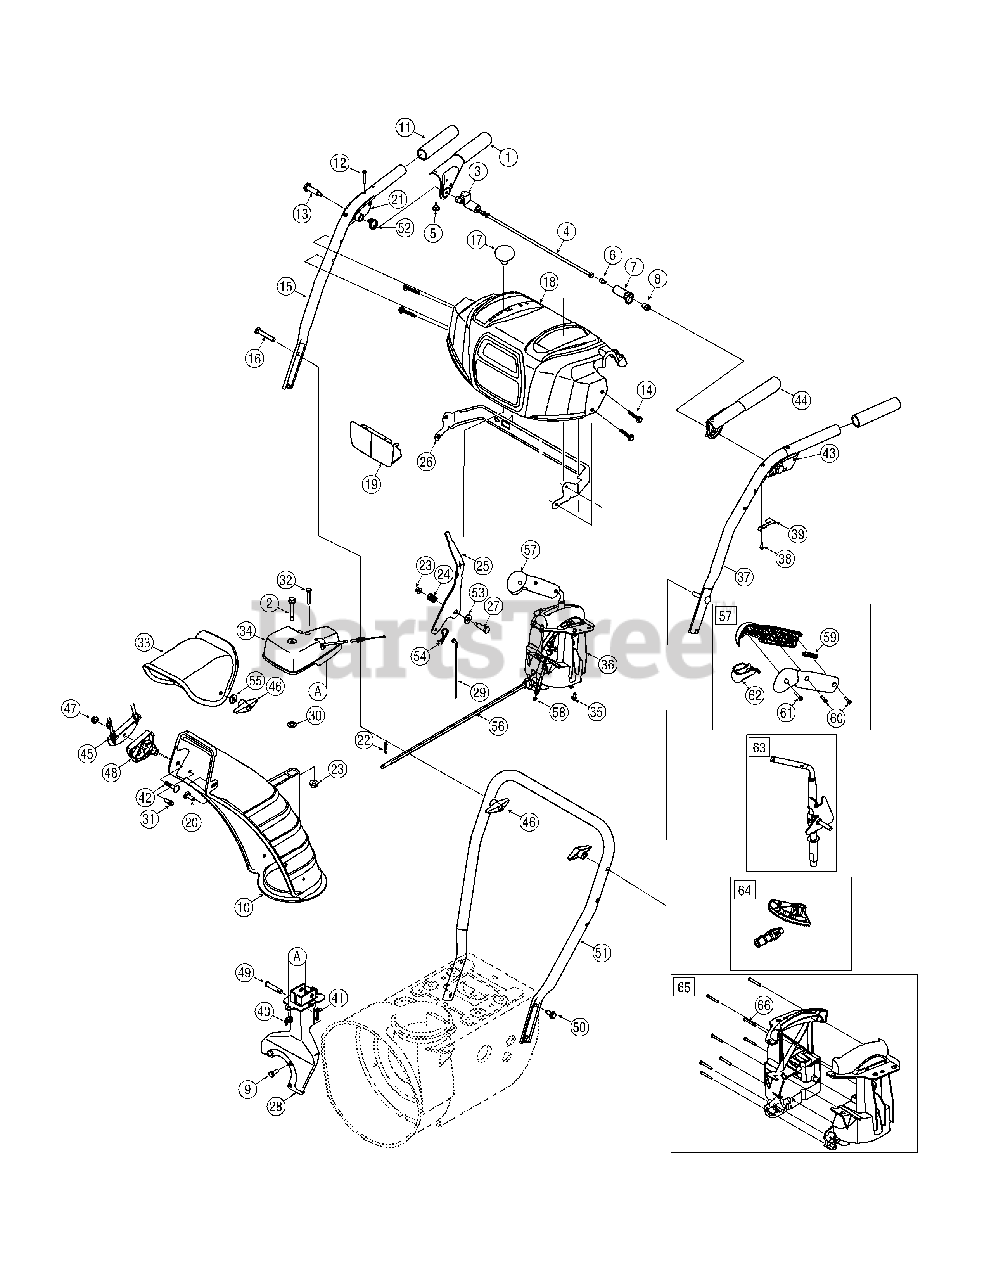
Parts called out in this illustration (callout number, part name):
1	Handle Engagement Assembly RH
2	Flange Shoulder Screw
3	Lock Plate
4	Pivot Rod
5	Rubber Bumper
6	Screw, 1/4-20 x .500
7	Clutch Lock Cam
8	Shoulder Nut, 1/4-20
9	Hex Screw, 5/16-24 x .750
10	Lower Chute
11	Handle Grip
12	Screw, #10-24 x 0.375
13	Shoulder Screw, 1/4-20
14	Screw, 1/4-20 x 1.625
15	Upper Handle RH
16	Carriage Screw, 5/16-18 x 2.25
17	Shift Knob
18	Handle Panel
20	Carriage Bolt, 5/16-18 x 1.0
21	Handle Clutch Lock RH Assy
22	Cotter Pin
23	Flange Lock Nut, 1/4-20
24	Compression Spring
25	Shift Lever
26	Panel Bracket
27	Shoulder Screw
28	Chute Support Bracket
29	Speed Selector Cable
30	Flat Washer, .25 x .630 x .0515
31	Hi-Lo Screw, 1/4-15 x .75
32	Hex Screw, 1/4-20 x 3.00
33	Upper Chute
34	4-Way Chute Gearbox Assembly
35	Hi-Lo Screw, 1/4-15 x 0.5
36	4-Way Chute Control™ Assembly
37	Upper Handle LH
38	Screw, #8-16 x 0.50
39	Clutch Lock Spring
40	Wing Nut, 1/4-20
41	Bow Tie Cotter Pin
42	Carriage Bolt, 5/16-18 x 1.50
43	Handle Clutch Lock LH Assy
44	Handle Engagement Assembly LH
45	Cable Bracket
46	Wing Knob
47	Flange Lock Nut, 5/16-18
48	Chute Tilt Cable Guide
49	Clevis Pin
50	Screw, 5/16-18 x 0.75
51	Lower Handle
52	Torsion Spring
53	Flat Washer
54	Click Pin
55	Flat Washer, .349 x .879 x .063
56	Chute Rod
57	Handle Assembly
58	4-Way Cable
59	Handle Plunger
60	Screw, Mach., #8-32 x .750
61	Screw, #8 x 1.00
62	Handle Lever
63	Shift Assembly
64	Gear Set Assembly
65	Handle Housing Assembly
66	Screw, #8-18 x 1.250
